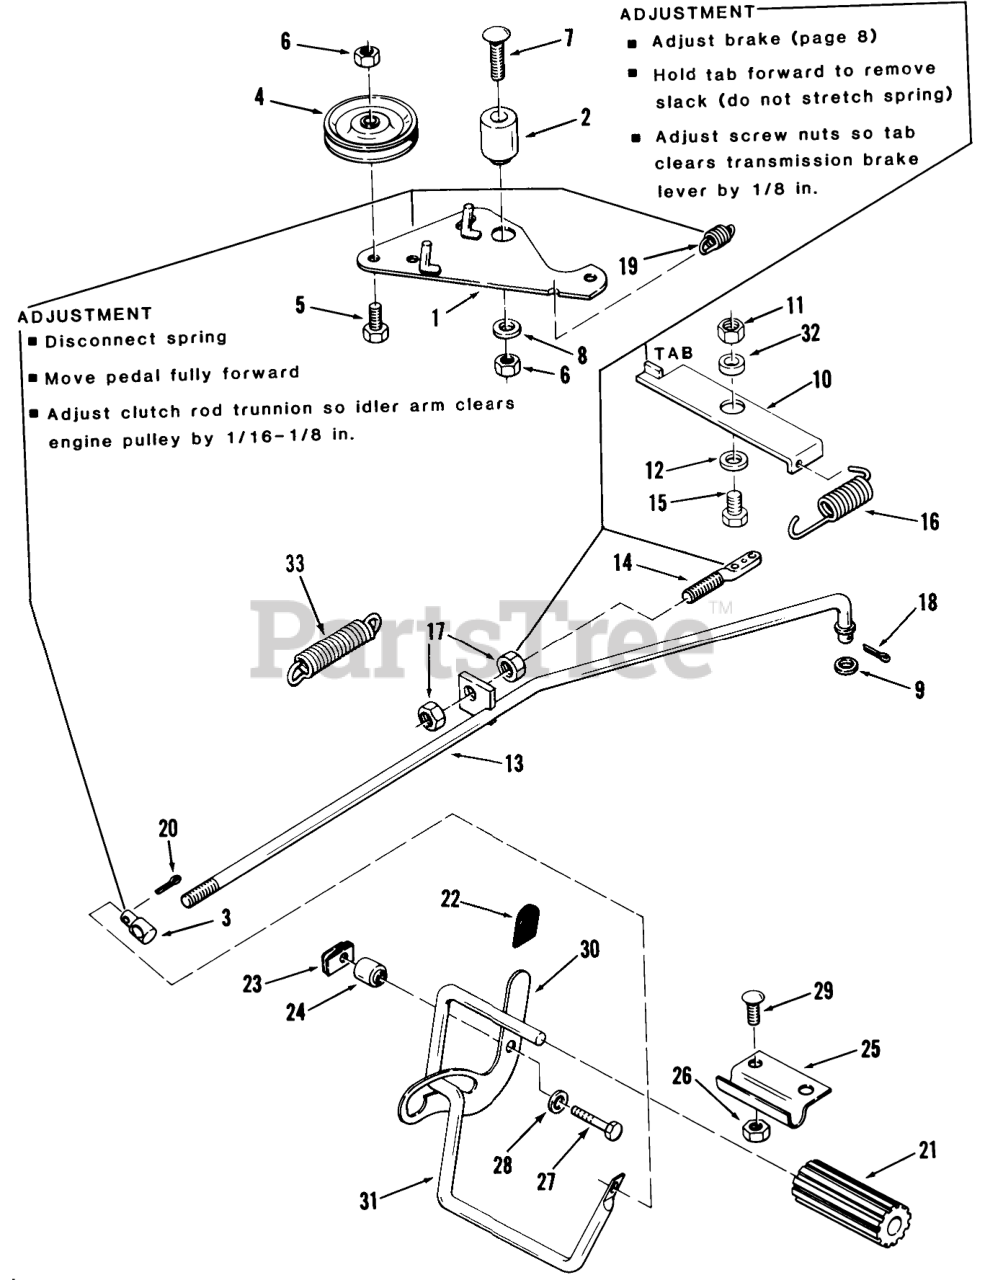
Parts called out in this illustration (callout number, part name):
1	ASSY-IDLER ARM
2	SPACER-CLUTCH ARM
3	TRUNNION
4	PULLEY-IDLER STATION
5	BOLT
6	Nut
7	Bolt
8	WASHER
9	Washer
10	Brake Rod
11	Nut
12	WASHER 5/16 SAE
13	Clutch Rod
14	Screw Adjustment
15	Bolt
16	Spring
17	Nut
18	Cotter Pin
19	SPRING
20	Cotter Pin
21	PAD-CLUTCH/BRKE PDL
22	GRIP
24	Spacer-Park Brake Lever
25	SPINDAL SUPPORT R
26	Nut
27	Bolt 1/4-20 X 1 1/2
29	Bolt-Carriage
30	Park Brake Lever
31	ROD-PEDAL
32	SPACER
33	SPRING-EXTENSION
